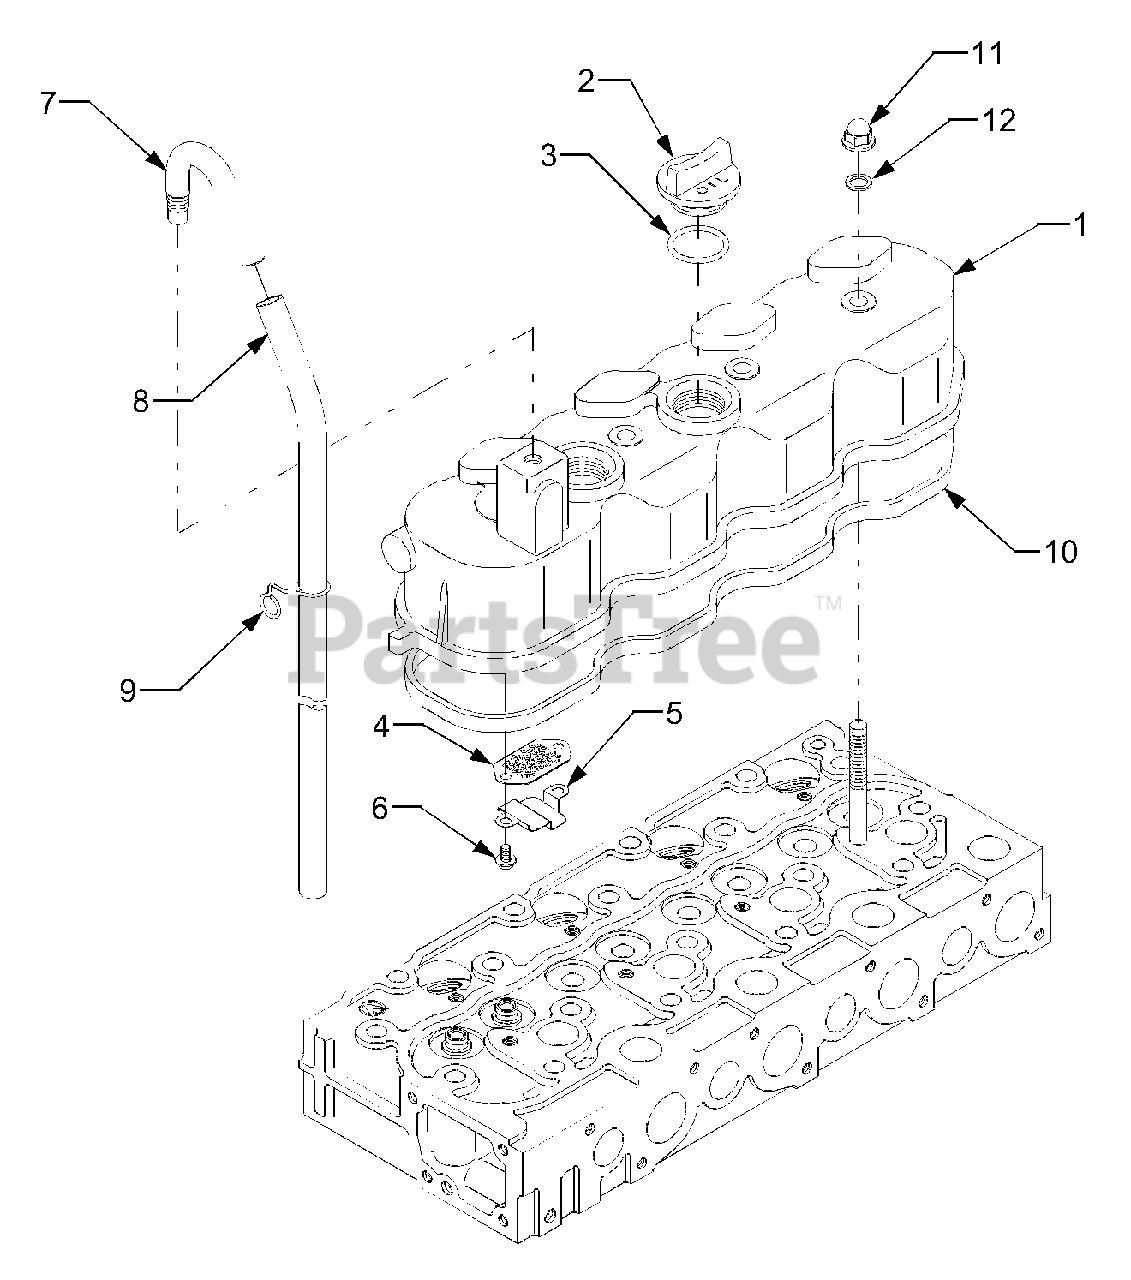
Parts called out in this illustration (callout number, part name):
1	Cover, Cylinder Head
2	Plug, Oil Filler
4	Plate, Element 1
5	Shield, Breather Oil
7	Joint, Breather Pipe
8	Pipe, Breather
10	Gasket, Head Cover
